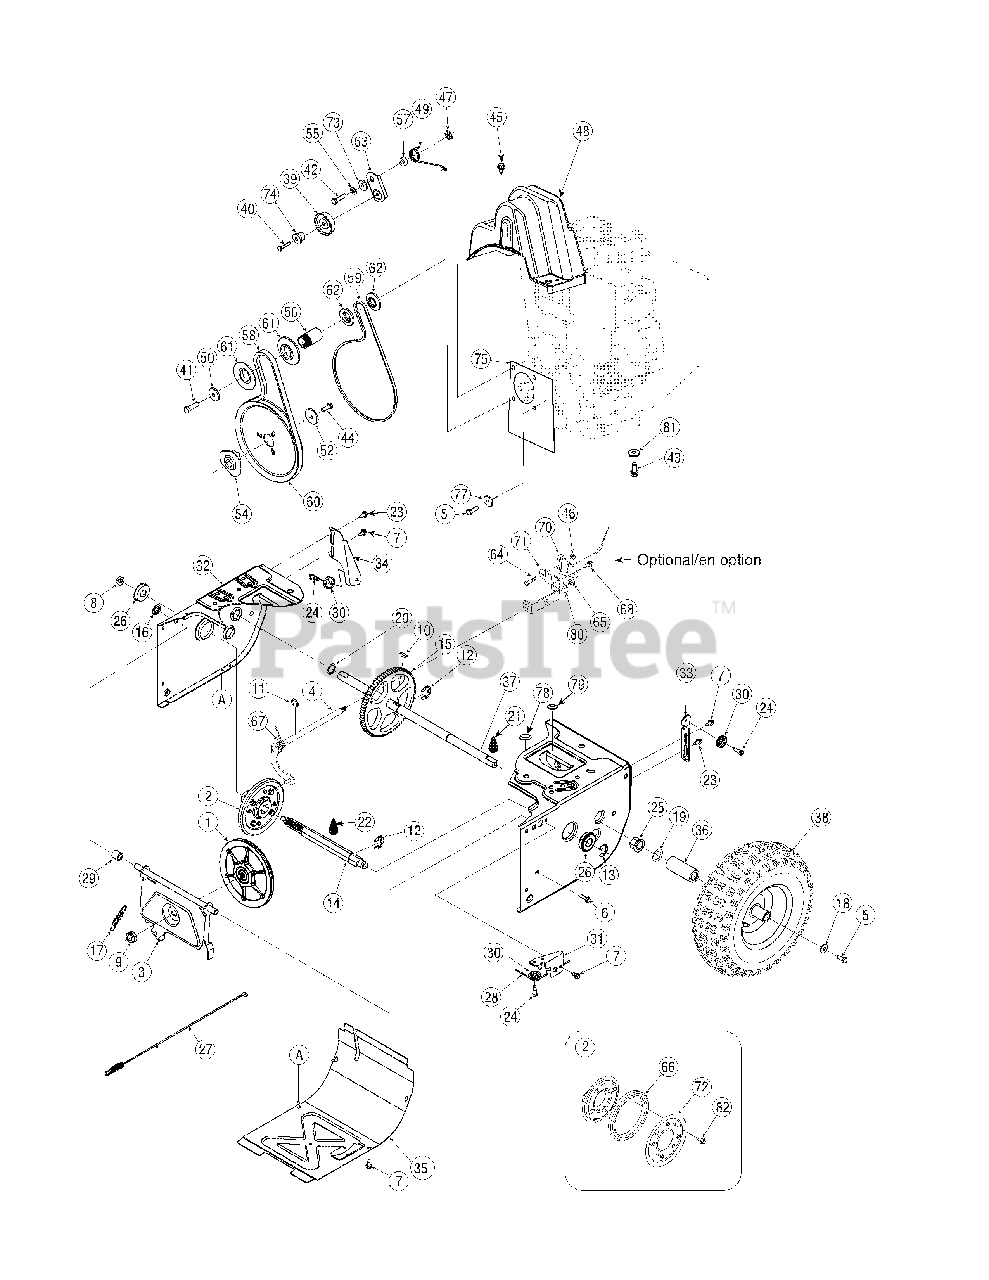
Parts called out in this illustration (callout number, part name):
1	Friction Wheel Disc Assembly
2	Friction Wheel Ass’y, Bearing 5.5 OD
4	Shift Rod Ass’y
5	Hex L-Bolt 5/16-24 x .75 Gr. 5
6	Hex Bolt 1/4-20 x 1.00
7	Hex Wash Hd TT Scr. 1/4-20 x .625
8	Flange Lock-Nut 3/8-16 Gr. F Nylon
9	Jam L-Nut 5/8-18
10	#9 HI-Pro Key 3/16 x 3/4 Dia HT
11	Retaining Ring
12	Retainer Ring
14	Hex Shaft .8125 - 7 tooth
15	Gear - 80 Tooth
16	Cap Speed Nut 1/4 Rod
17	Extension Spring 3/8 OD x 2.50
18	Cupped Washer .345 ID x .88 OD x .060
19	Flat Washer .79 ID x 1.25 OD x .06
20	Flat Washer .75 x 1.00 x .06
21	Grease
22	Rust Preventative Oil
23	Shoulder Screw .373 x .105:TT 1/4-20
24	Hex Shld.Scr.1/4-28 x .375
25	Hex. Flange Bearing.751" ID
26	Ball Bearing w/snap ring
27	Drive Clutch Cable 44.83" Lg.
28	Auger Clutch Cable 47.23" Lg.
29	Spacer .513 ID x 1.0
30	Cable Guide Roller
34	Guide Bracket - Drive Cable
37	Axle .75 X 22" Lg.
39	Idler Pulley Assembly 1.917 OD
40	Hex Screw 1/4-20 x 1.25
41	Hex Screw 3/8-24 x 1.25
42	Hex Hd Cap Scr. 5/16-24 x 1.25 Gr. 5
43	Hex Wash HD Tap Scr 3/8-16 x .88
44	Hex Bolt 5/16-24 x 0.875
45	Hex Wash Hd TT Scr. 1/4-20 x .625
46	Hex L-Flanged Nut 1/4-20 Gr. F Nylon
48	Belt Cover
48	Belt Cover (w/4 way chute control)
49	Torsion Spring .850 ID x .354" Lg.
50	Flat Washer .40 ID x 1.25 OD x .160
51	Flat Washer .330 ID x .630 OD x .0635
52	Flat Washer .34 x 1.50 x .150
53	Grease:Arctic:EP NLGI 1-58F
54	Pulley Adapter
55	Lockwasher 5/16
56	Spacer .875 ID x 1.185 OD
57	Spacer .340 x .750 x .360" Lg.
58	Belt .5 x 35.0" Lg.
59	Belt 34.4" Lg.
61	Pulley Half
62	Pulley Half 3/8 V x 1.71 OD
63	Wheel Drive Idler Bracket
64	Hex Bolt 1/4-20 x .62 Gr. 5
65	Flange Locknut 5/16-18 Gr. F, Nylon
66	Friction Wheel Rubber
67	Torsion Spring .750 ID x .968" Lg.
68	Shoulder Screw .373 x .105:TT 1/4-20
69	Hex. Hd. Cap Scr. M8-1.25:20 Gr. 8
72	Friction Plate
73	Shld. Spacer .3175 x .5 x .1025
76	Cable Control Wire
77	Shoulder Spacer
80	Flat Washer .469 x .875 x .105
81	Flat Washer .38 x 1.38 x .125
82	Hex Wash. Hd. TT Scr. 1/4-14 x .625
